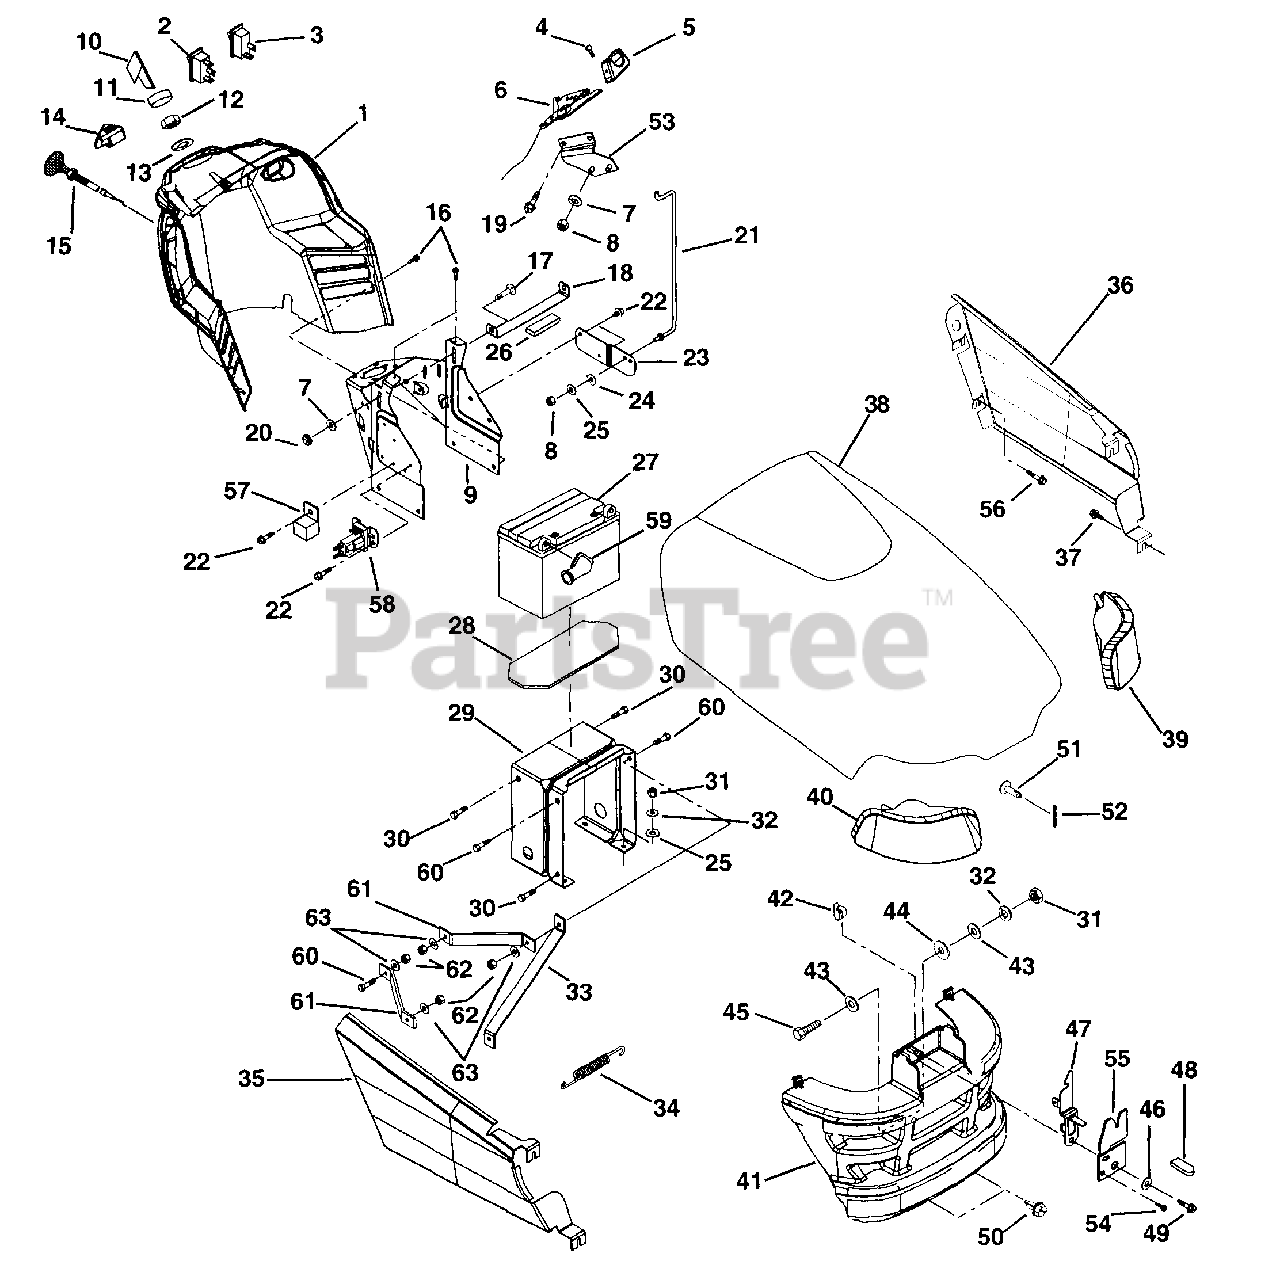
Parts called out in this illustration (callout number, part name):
1	Dash
2	Switch-Cruise
3	Switch-Light
4	Screw-Set 10-24 x .38
5	Knob-Throttle
6	Cable-Throttle
7	Washer-Flat-Steel .323 x .625 x .062
8	Nut-Locking-Center .250-20
9	Support-Dash-Top
10	Key-w/Cap
11	Cap-Ignition Switch
12	Nut-Panel .562-24
13	Washer-Lock Internal .625 x .045
14	PTO Knob/Shaft Assembly
15	Choke Cable
16	Screw-Tapping 10-24 x .484 Hex Washer Head
17	Bolt-Round Head Square Neck .312-18 x .75
18	Holddown-Battery
19	Screw-Tapping .250-20 x.37
20	Nut-Locking-Nylon .31-18
21	Rod-Hood, Prop
22	Screw-Tapping 10-24 x .37 Hex Washer Head
23	Mount-Prop Rod
24	Wave Washer
25	Washer-Flat-Steel .312 x .734 x .065
26	Pad-Foam
27	Battery w/Tube
28	Rubber Pad
29	Support-Dash Base
30	Screw-Tapping .312-18 x .50 Hex Washer Head
31	Nut-Hex .31-18
32	Washer-Lock .312 x .097
34	Spring-Tension .035 x .45 x 2.75
35	Side Panel-Right Hand
36	Side Panel-Left Hand
37	Screw-Tapping 12-16 x .500
38	Hood with Decals-GLT
39	Headlight-Left Hand
40	Headlight-Right Hand
41	Grille
42	Clip-Harness
43	Washer-Flat-Steel .328 x 1.00 x .094
44	Washer-Flat-Nylon .375 x 1.00 x .062
45	Bolt-Hex .31-18 x 1.00 Grade 5
46	Washer-Flat-Steel .281 x 1.250 x .048
47	Hood Latch
48	Grip .062 x .375 x .750
49	Screw-Tapping 12-24 x .50 Hex Washer Head
50	Screw-Tapping .312-18 x .50 Hex Washer Head
51	Clevis Pin .243/.248 x 1 1/2
52	Pin-Cotter .09 x .75
53	Brace-Throttle Control
54	Screw-Tapping 10-12 x .50
55	Locator-Hood
56	Screw-Tapping 10-16 x .62
57	Relay
58	Solenoid
59	Insulator
60	Bolt-Hex .31-18 x .75 Grade 5
61	Bracket-Steering Assembly
62	Nut-Lock-Jam-Center .375-16
63	Washer-Flat-Steel .344 x .688 x .065
